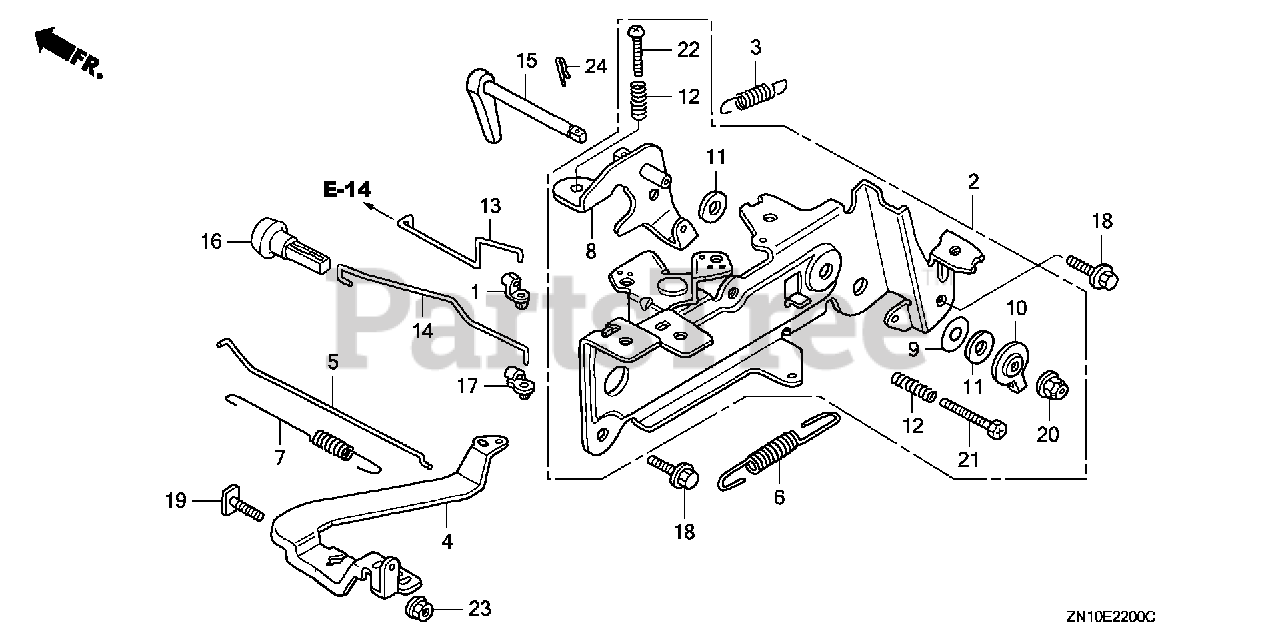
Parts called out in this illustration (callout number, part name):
1	JOINT, ROD
2	CONTROL ASSY.
3	SPRING, STARTER
4	ARM, GOVERNOR
5	ROD, GOVERNOR
6	SPRING, GOVERNOR (MANUAL)
7	SPRING, THROTTLE RETURN
8	ARM, CONTROL
9	SPRING, LEVER
10	WASHER, CONTROL ARM
11	SPACER, CONTROL LEVER
12	SPRING, CONTROL ADJUSTING
13	ROD, CHOKE CONTROL
14	ROD, CHOKE KNOB
15	LEVER ASSY., THROTTLE
16	KNOB, CHOKE
17	BUSH, LINKAGE
18	BOLT, FLANGE (6X14) (CT200)
19	BOLT, GOVERNOR ARM
20	NUT, SELF-LOCK (6MM)
21	BOLT, RECESSED (5X25)
22	SCREW, PAN (5X25)
23	NUT, FLANGE (6MM)
24	PIN, LOCK (10MM)
